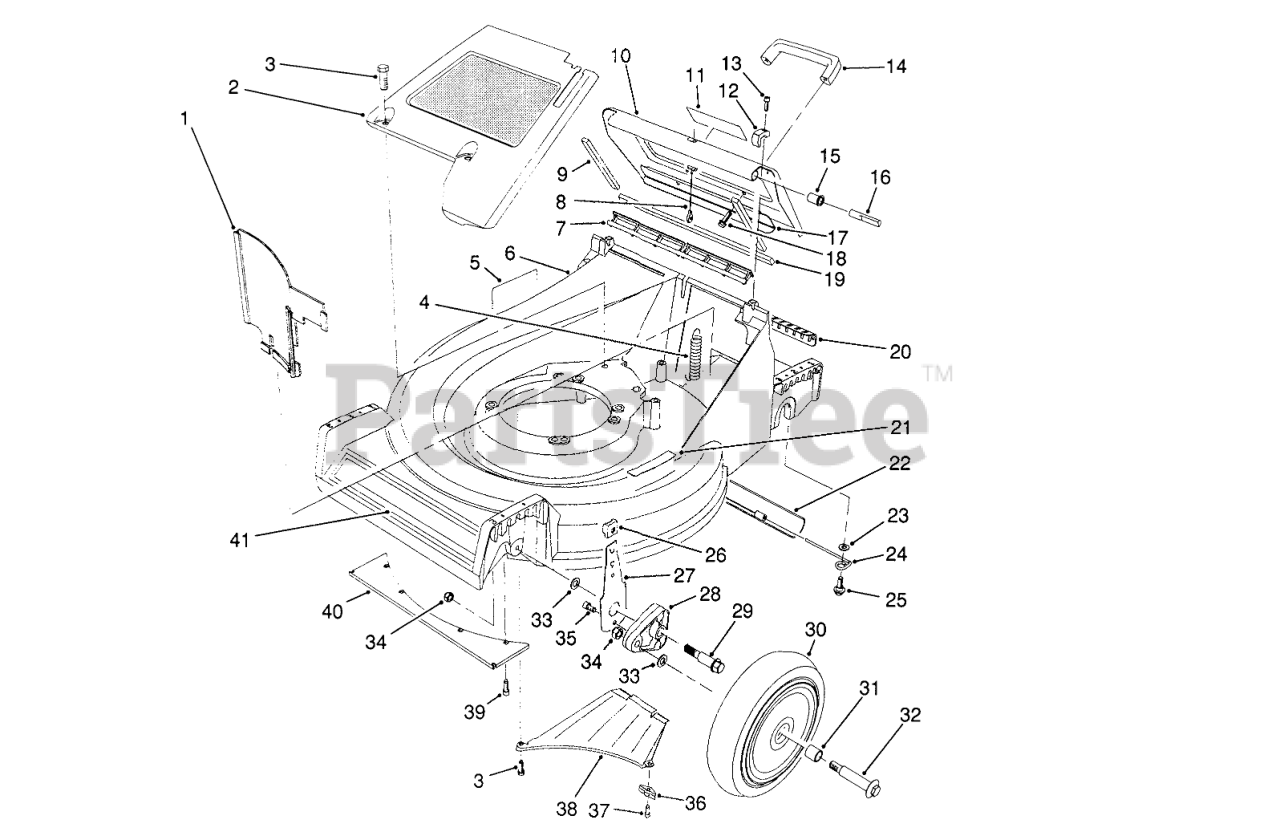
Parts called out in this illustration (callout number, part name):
1	PANEL-VERTICAL
2	PaneI-Screen
3	SCREW-HWHTF
4	EXTENSION-SPRING
5	Decal Danger
6	Housing-53cm (Model 26625B Only) (Incl. Ref. #5 & 21)
7	DOOR SEAL
8	DOOR CABLE
9	DOOR SIDE SEAL
10	Door-Discharge (Incl. Ref. #9, 11 & 19)
11	DECAL - DANGER
12	HINGE CLAMP
13	SCREW-HSH
14	HANDLE-DOOR
15	DOOR BUSHING
16	HINGE PIN
17	DOOR - BRACE
18	SCREW-HWH
19	DOOR END SEAL
20	ACCESS COVER
21	DECAL - STEP PAD INT'L
22	TRAILING SHIELD
23	WASHER-PLAIN
24	SHIELD HANGER
25	SCREW-SHOULDER
26	KNOB-ARM
27	FRONT SPRING ARM ASM
28	ARM-PIVOT, FRONT
29	BOLT-SHOULDER
30	Wheel & Tire Assembly (Incl. Ref. #31)
31	BUSHING
32	WHEEL BOLT
33	WASHER
34	Nut
35	SCREW-HSH, THREAD FORMING
36	Bracket-Discharge
37	SCREW-HWHTF
38	Ramp Discharge
39	SCREW-HWH
40	FRONT GUARD
41	DECAL - 53 CM
